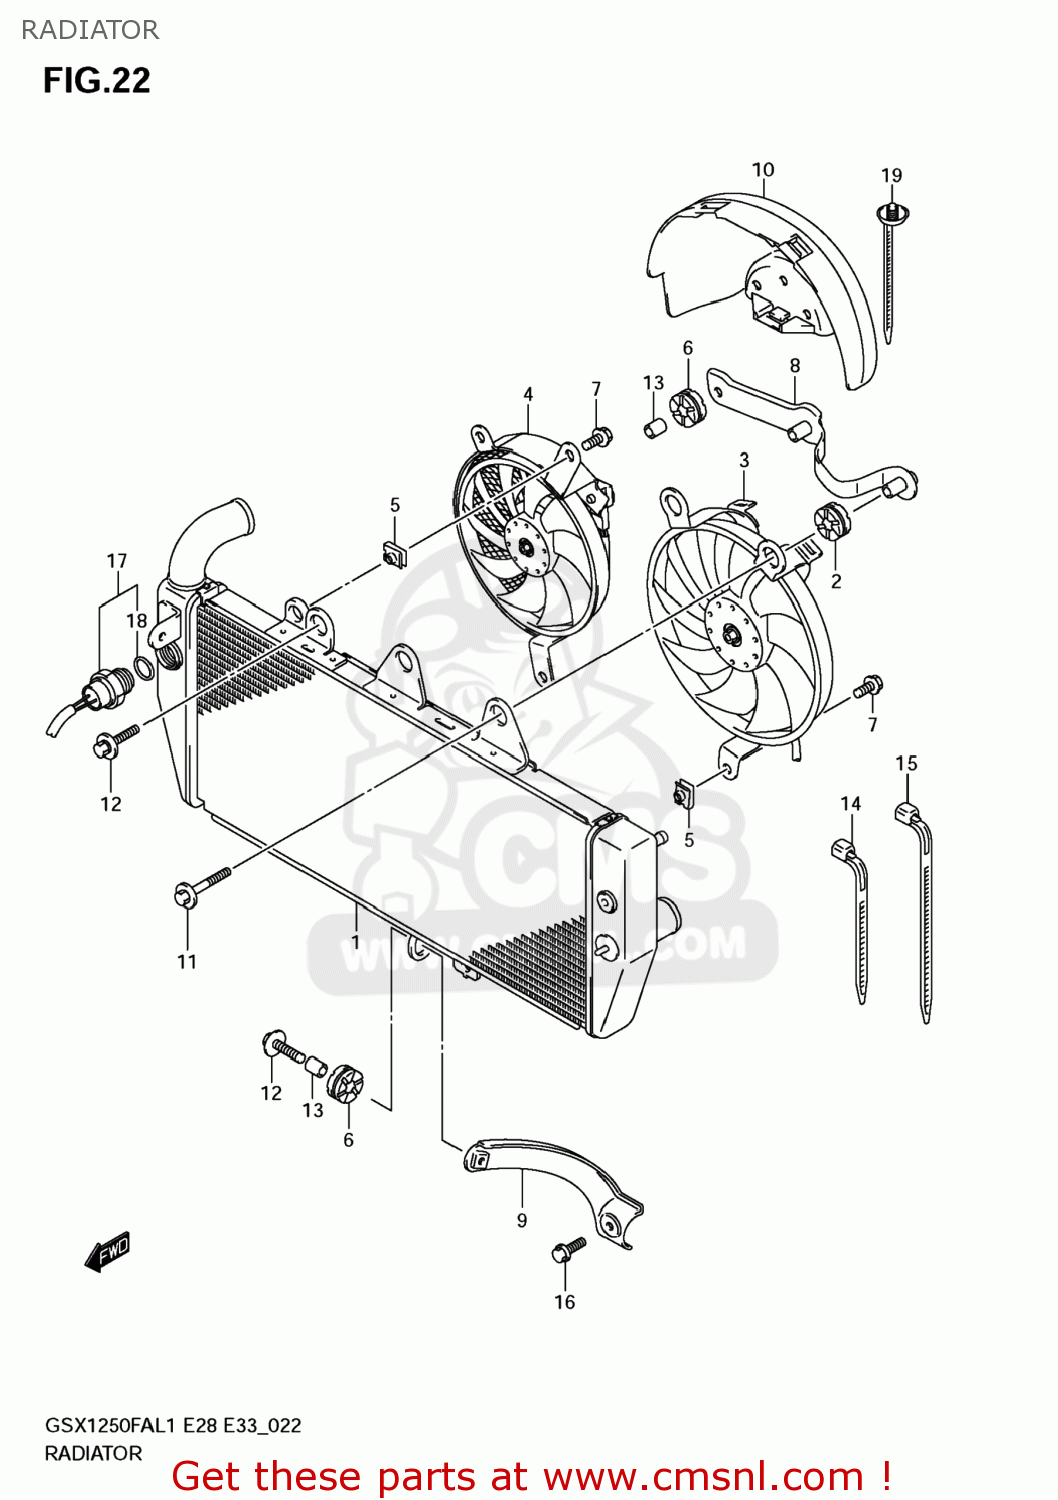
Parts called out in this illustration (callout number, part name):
1	RADIATOR ASSY,WATER
2	CUSHION,RADIATOR UPR
3	FAN ASSY,RADIATOR
4	FAN ASSY,RADIATOR
5	NUT,RADIATOR FAN
6	CUSHION
7	BOLT
8	BRACKET,RADIATOR UPR
9	BRACKET,RADIATOR
10	SHIELD,RADIATOR HEAT
11	BOLT(6X37)
12	BOLT(6X25)
13	SPACER(6.5X10X12)
14	CLAMP(L:125)
15	CLAMP(L:165)
16	BOLT
17	SWITCH,RADIATOR FAN
18	O RING
19	CLAMP(L:154)
